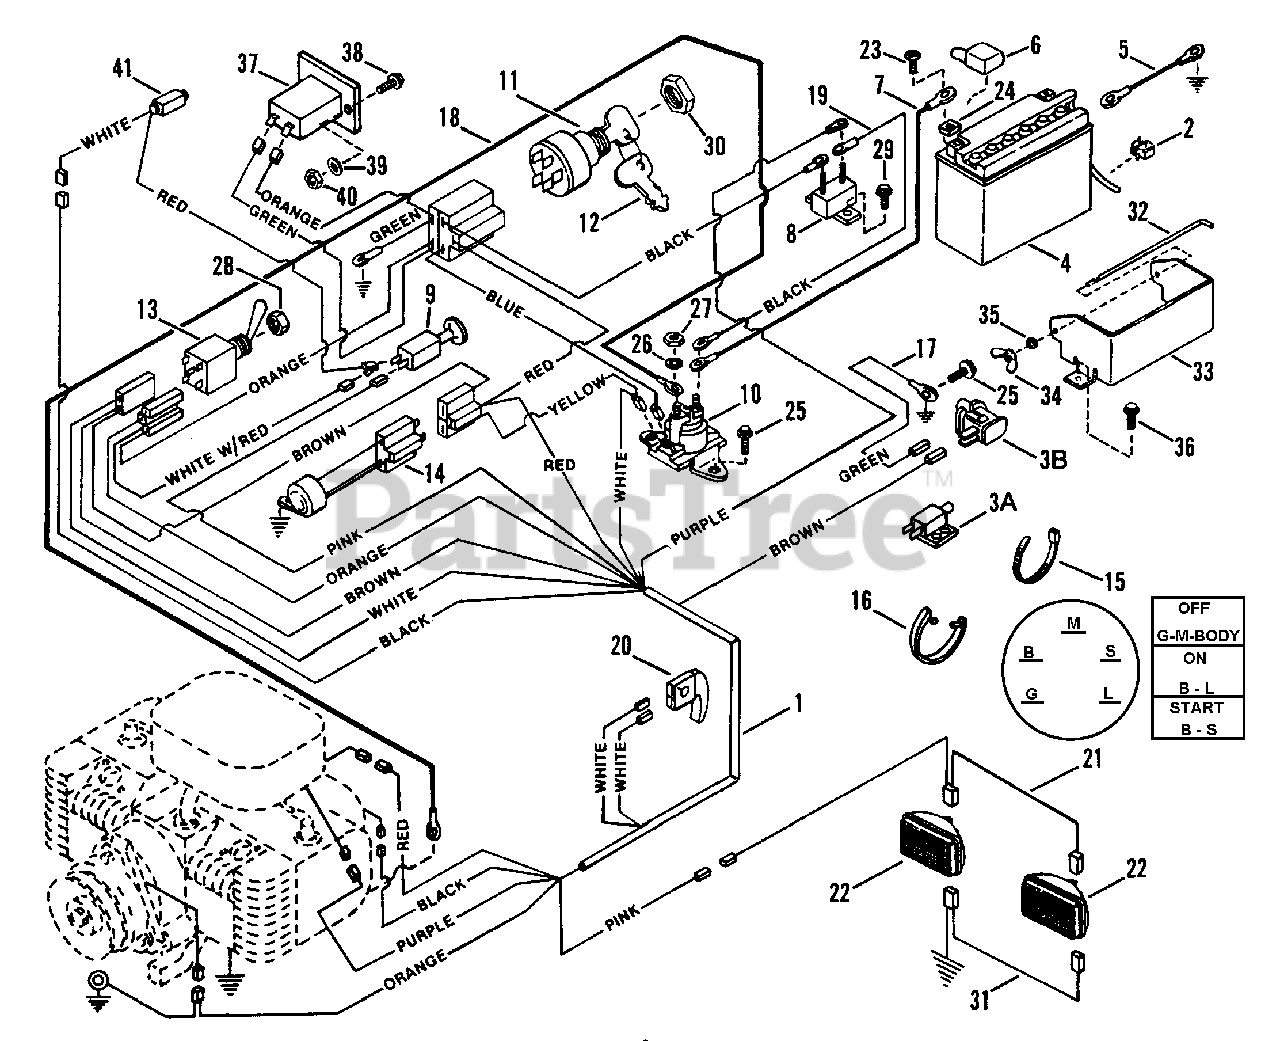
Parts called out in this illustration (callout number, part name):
1	HARNESS, Wiring
2	CLIP, Battery Hose
3A	SWITCH, Seat Interlock
3B	SWITCH, Seat
4	KIT, Battery 12 Volt, 20 AMP HR
5	CABLE, Negative (Black)
6	COVER, Positive Terminal
7	CABLE, Solenoid/Battery (11")
8	CIRCUIT-BREAKER
9	SWITCH, Headlamp
10	SOLENOID
11	KEYSWITCH
12	KEY
13	SWITCH, PTO
14	MODULE, Interlock
15	TIE, Wire
16	TIE, Cable
17	WIRE, Seat Switch to Ground
18	CABLE, Solenoid/Starter (36")
19	WIRE, Breaker to Solenoid
20	SWITCH, Clutch Interlock
21	HARNESS, Headlamp
22	HEAD-LAMP
23	SCREW, M5 x 10 P.H. Torx
24	NUT, M5 x .08, Battery Term.
25	SCREW, 1/4-20 x 5/8" S.T.
26	WASHER, 1/4 Int. Tooth Lock
27	NUT, Special 1/4-20 Hex
28	NUT, Special 1/2-27 Hex
29	SCREW, #10-24 x 1/2" Hex Washer Self-Tap (Torx)
30	NUT, 5/8-32 Hex
31	HARNESS, Ground
32	CLAMP, Battery
33	BRACKET, Battery
34	WING-NUT, 1/4-20
35	WASHER, 1/4 Flat
36	SCREW, 1/4-20 X 5/8" S.T.
37	HOURMETER
38	SCREW, #6-32 x 3/4" Machine
39	WASHER, #6 Internal Tooth Lock
40	NUT, #6-32 Hex
41	OIL LIGHT
